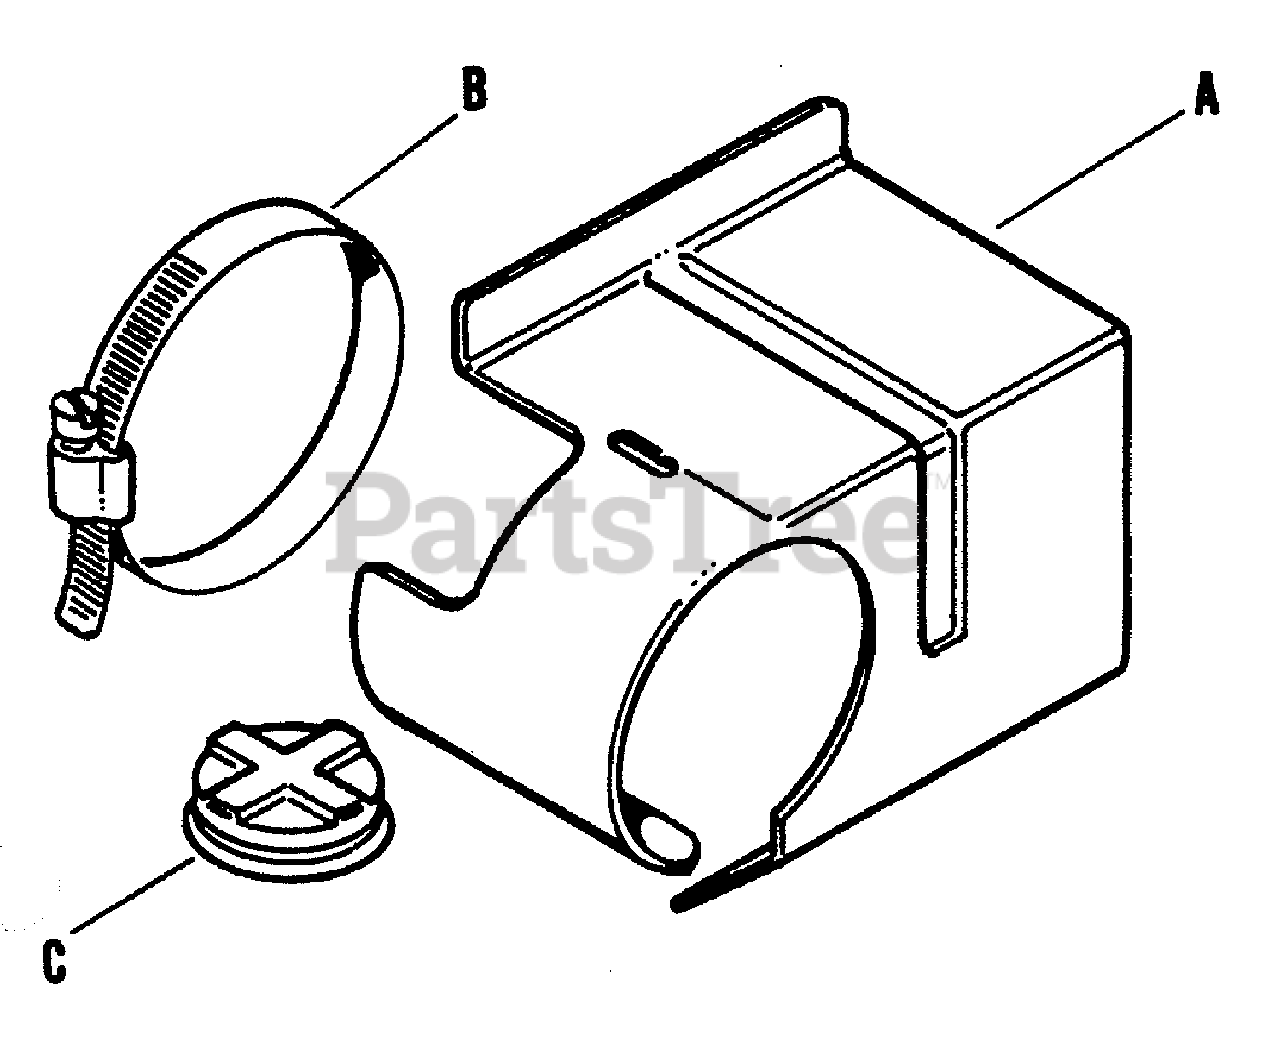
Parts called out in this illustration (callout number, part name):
A	DEFLECTOR, Heat
B	DEFLECTOR, Clamp
C	CAP, Gas (Winterized)
